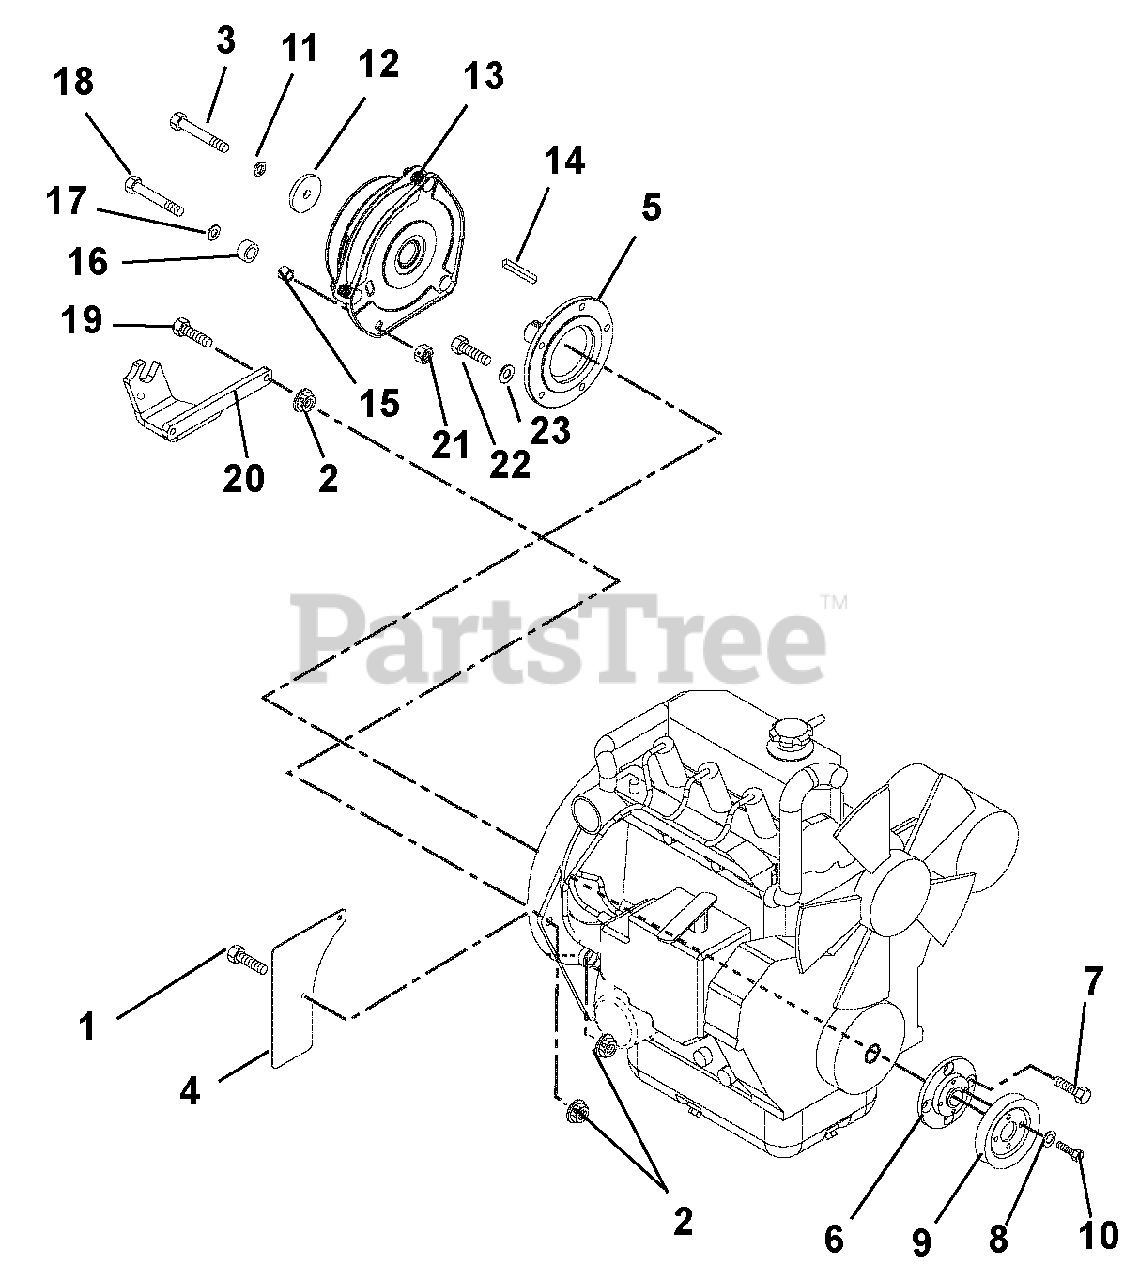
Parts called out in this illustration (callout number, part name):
1	Bolt, Hex .31-18 x .75 Grade 5
2	Nut, Locking Top Flange .31-18
3	Bolt, Hex .44-20 x 2.50 Grade 5 YZ EP80
4	Guard, Flywheel
5	Stub Shaft
6	Adapter, Sheave
7	Bolt, M8 1.25 x 25
8	Washer, Locking .25 x .062
9	Sheave, Poly V 1.0 x 3.25
10	Bolt, Hex .25-20 x .75 Grade 5
11	Washer, Locking .44 x .109 Regular
12	Washer, Flat Steel .469 x 2.00 x .25
13	Clutch, Ogura
14	Key .25 x .25 x 2.25
15	Spacer .375 x .688 x .500
16	Bumper, Rubber .62 x 1.0 x .51
17	Washer, Flat Steel .406 x .812 x .065
18	Bolt, Hex .38-16 x 1.00 Grade 5
19	Bolt, Hex .31-18 x 1.25 Grade 5
20	Bracket, Clutch Stop
21	Nut, Lock .375-16
22	Bolt, Hex M8 x 1.25 x .75 Gade 8
23	Washer, Lock .31 x .078 Reg
